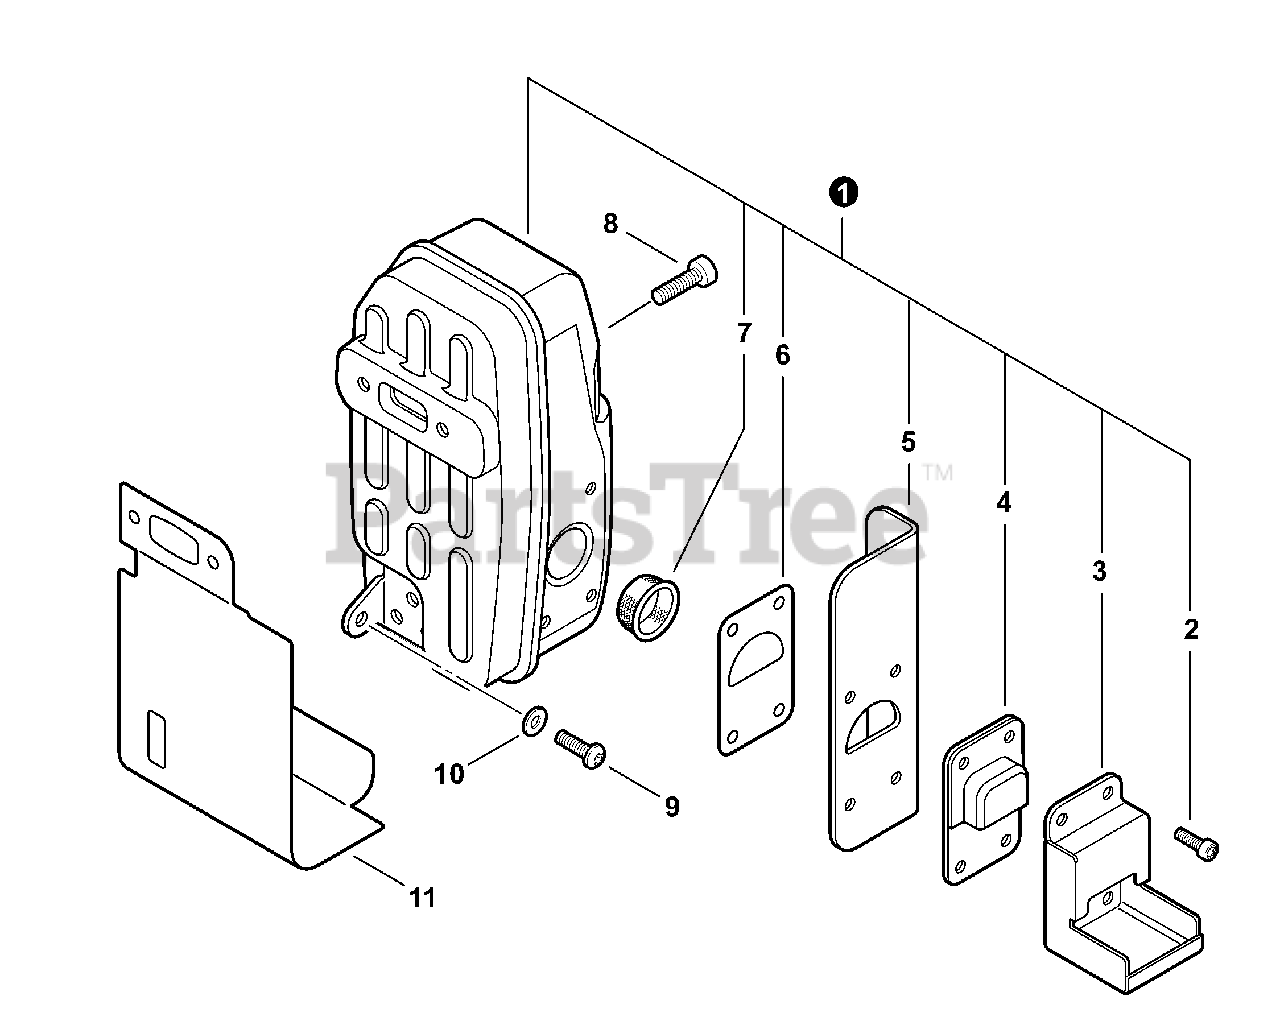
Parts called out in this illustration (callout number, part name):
1	MUFFLER ASSY
2	SCREW - 4×12
3	GUIDE, EXHAUST
4	GUIDE, EXHAUST
5	SHIELD, EXHAUST
6	GASKET, EXHAUST
7	SCREEN, SPARK ARRESTOR
8	SCREW - 6×20
9	SCREW - 5×16
10	WASHER - 5
11	SHIELD, EXHAUST
